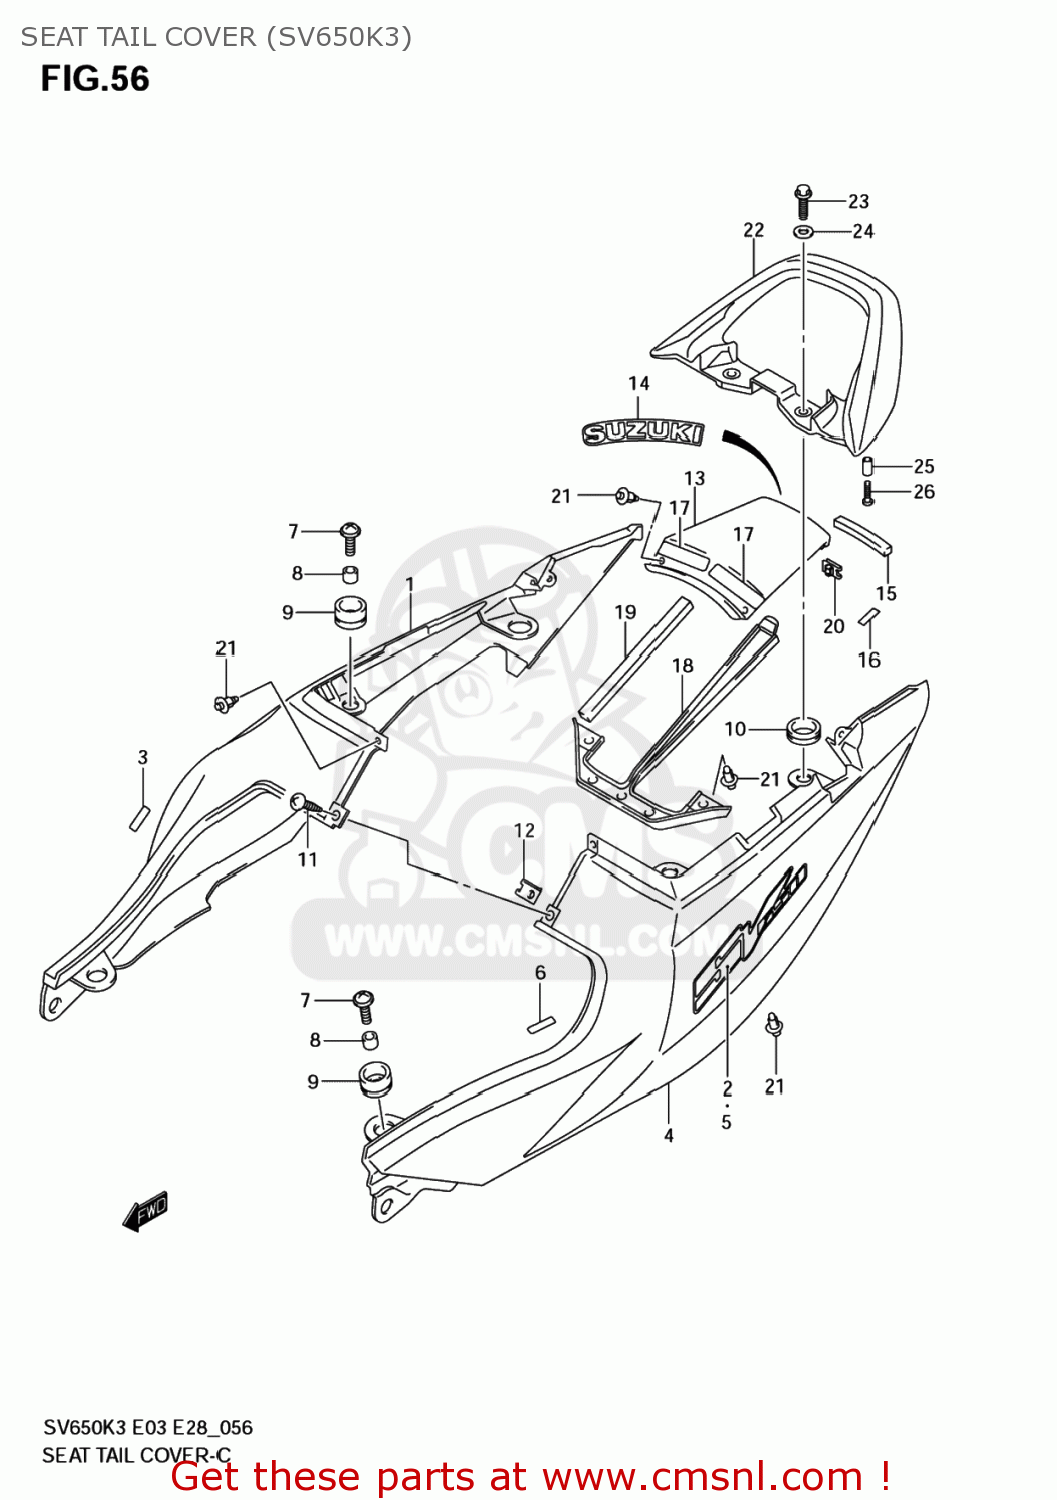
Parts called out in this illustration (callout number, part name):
1	COVER,SEAT TAIL
2	EMBLEM,SEAT TAIL COVER
3	TAPE,COVER
4	COVER,SEAT TAI
5	EMBLEM,SEAT TAIL COVER
6	TAPE,COVER
7	SCREW(6X20)
8	SPACER(6.5X10X9.4)
9	CUSHION
10	CUSHION
11	SCREW
12	NUT
13	COVER,SEAT TAIL CTR
14	EMBLEM,SUZUKI
15	CUSHION,SEAT TAIL COVER CTR
16	TAPE,SEAT TAIL COVER
17	TAPE,COVER
18	COVER,SEAT TAIL RR
19	CUSHION,SEAT TAIL COVER
20	NUT
21	CLIP(BLACK)
22	HANDLE,PILLION RIDER
23	BOLT
24	WASHER(8.5X24X2.3)
25	SPACER(6.5X9X18)
26	SCREW(6X25)
